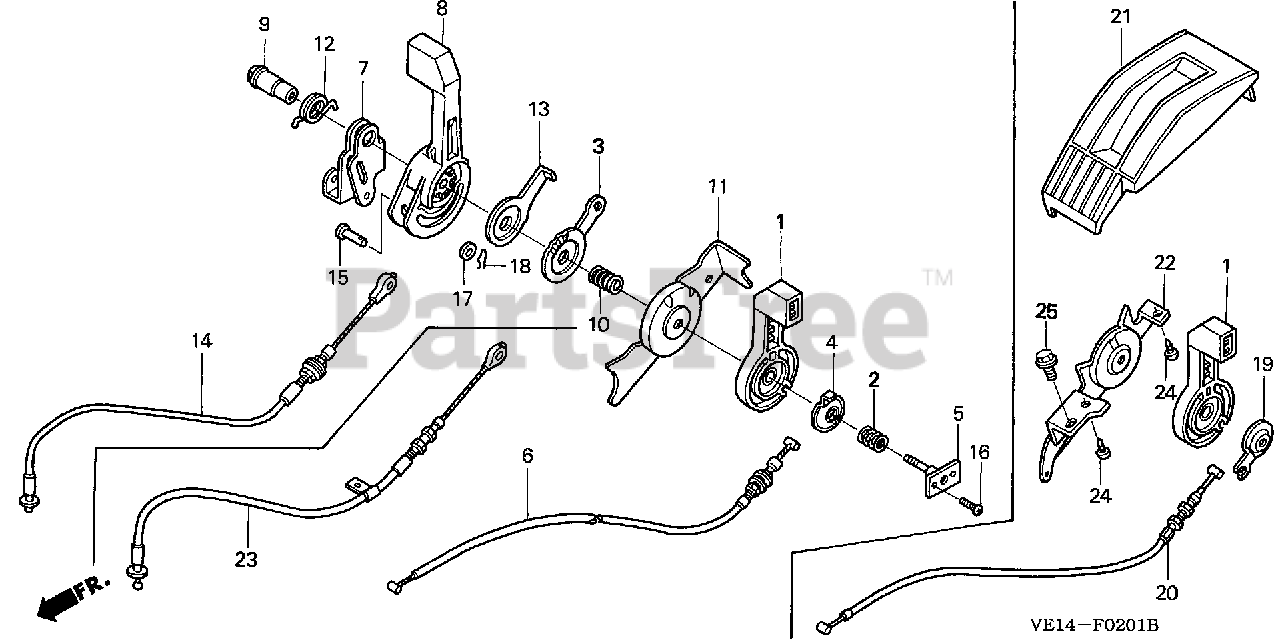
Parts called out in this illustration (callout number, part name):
1	LEVER, THROTTLE
2	SPRING, THROTTLE LEVER
3	SEAT, SPRING
4	SEAT, SPRING
5	PIN, THROTTLE LEVER
6	CABLE, THROTTLE
7	ARM, CHANGE LEVER
8	LEVER, CHANGE
9	NUT, CHANGE LEVER
10	SPRING, CHANGE LEVER
11	PLATE, STOPPER
12	SPRING, ARM RETURN
13	PLATE, THRUST
14	CABLE, CHANGE
15	PIN (6X22)
16	SCREW, PAN (6X32)
17	WASHER, PLAIN (6MM)
18	PIN, LOCK (6MM)
